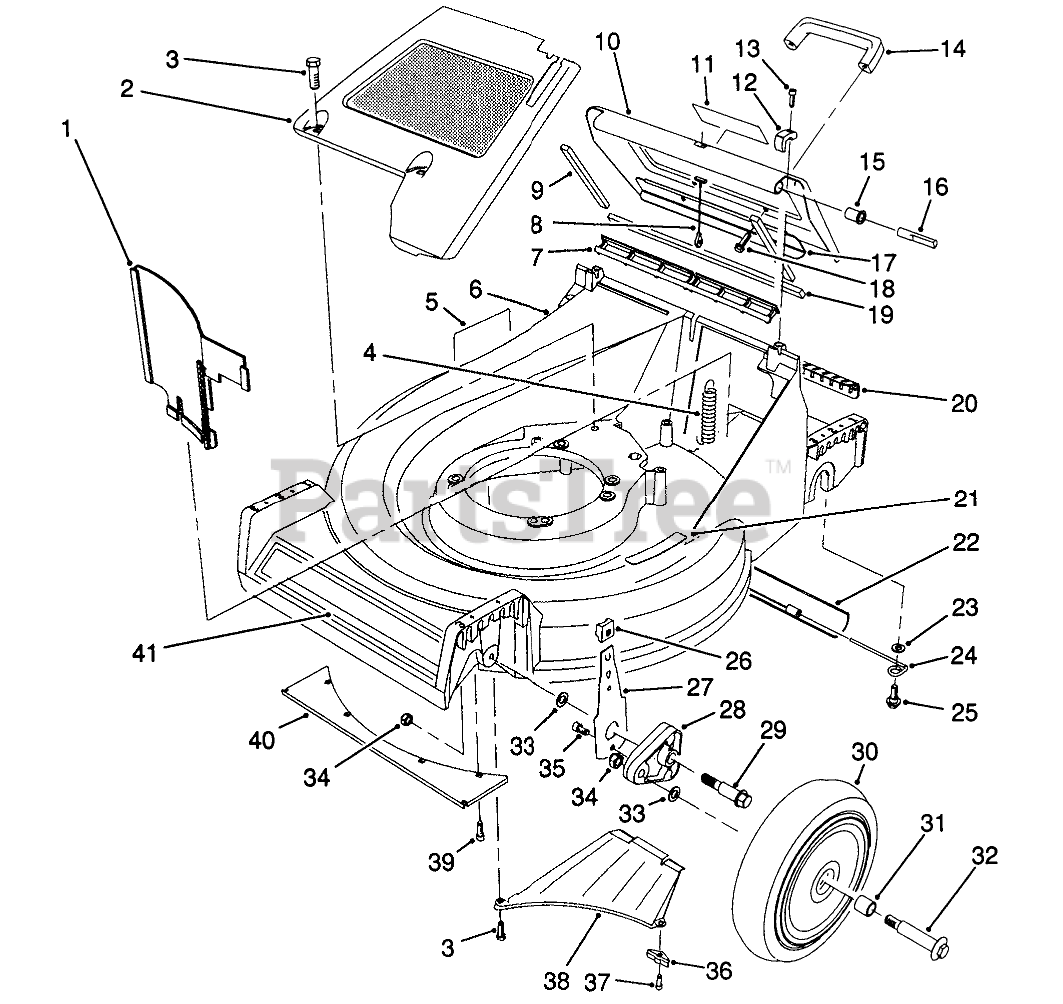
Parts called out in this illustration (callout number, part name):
1	PANEL-VERTICAL
2	PaneI-Screen
3	SCREW-HWHTF
4	EXTENSION-SPRING
5	Decal Danger
6	Housing-53cm (Model 26625B Only) (Incl. Ref. #5, 21 & 41)
7	DOOR SEAL
8	DOOR CABLE
9	DOOR SIDE SEAL
10	Door-Discharge (Incl. Ref. #9, 11 & 19)
11	DECAL - DANGER
12	HINGE CLAMP
13	SCREW-HSH
14	HANDLE-DOOR
15	DOOR BUSHING
16	HINGE PIN
17	DOOR - BRACE
18	SCREW-HWH
19	DOOR END SEAL
20	ACCESS COVER
21	DECAL - STEP PAD INT'L
22	TRAILING SHIELD
23	WASHER-PLAIN
24	SHIELD HANGER
25	SCREW-SHOULDER
26	KNOB-ARM
27	FRONT SPRING ARM ASM
28	ARM-PIVOT, FRONT
29	BOLT-SHOULDER
30	Wheel & Tire Assembly (Incl. Ref. #31)
31	BUSHING
32	WHEEL BOLT
33	WASHER
34	NUT-LOCK
35	SCREW-HSH, THREAD FORMING
36	Bracket-Discharge
37	SCREW-HWHTF
38	Ramp Discharge
39	SCREW-HWH
40	FRONT GUARD
41	DECAL - 53 CM
